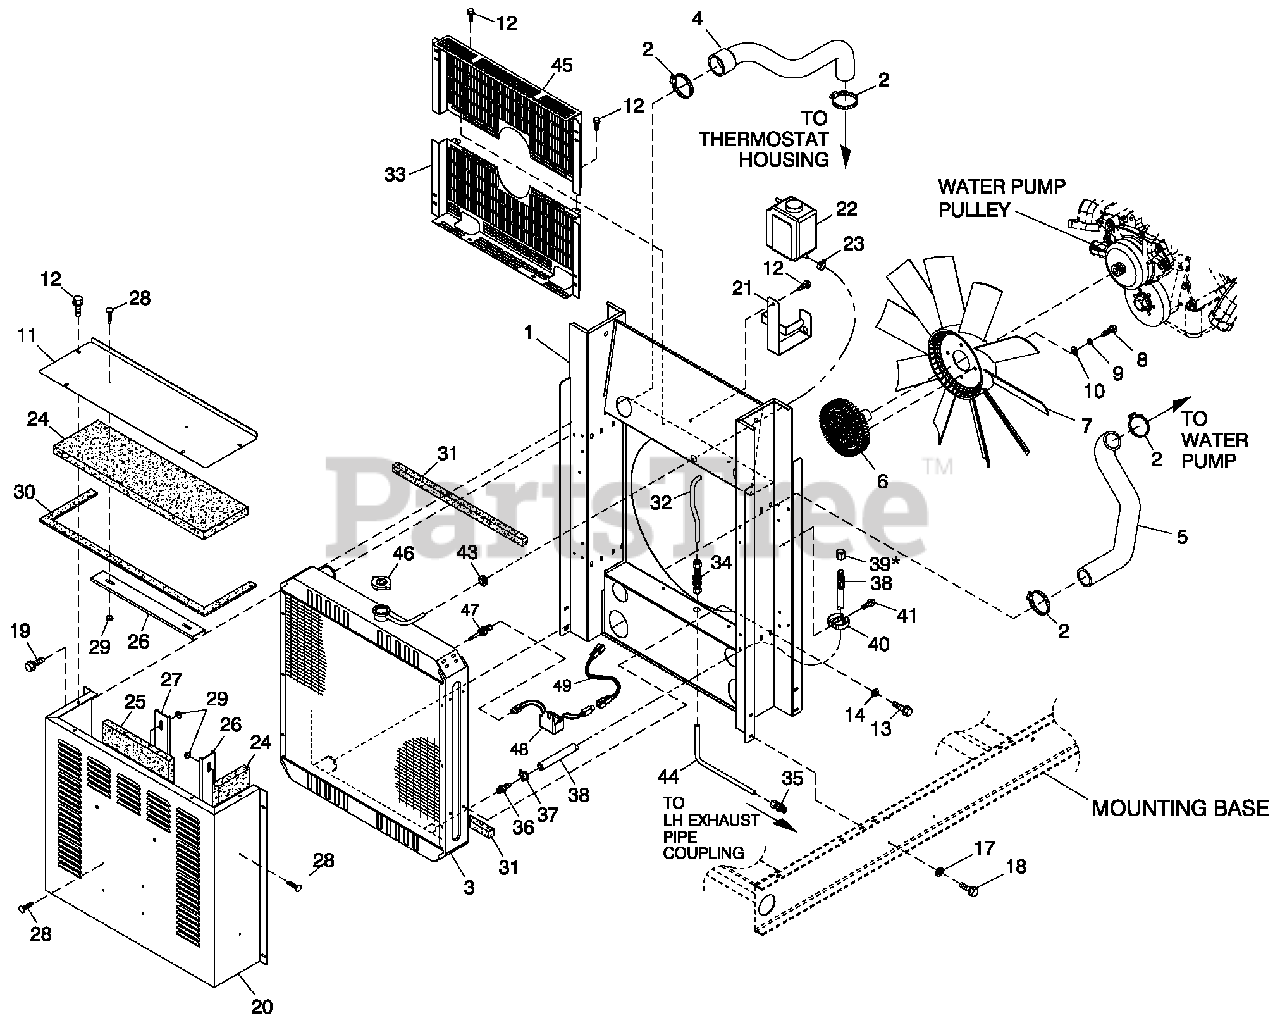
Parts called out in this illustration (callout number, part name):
1	WELDMENT RAD SUPPORT 3.9L C2
2	CLAMP HOSE #28 1.32-2.25
3	RADIATOR 598 X 568 X 49 CPL RH
4	HOSE UPPER RAD CPL C2 3.9L
5	HOSE LOWER RAD CPL C2 3.9L
6	CLUTCH COOLING FAN
7	FAN 22" DIA 10 BLADE
8	SCREW HHC M10-1.5 X 20 G8.8
9	WASHER LOCK M10
10	WASHER FLAT 3/8-M10 ZINC
11	DUCT INNER DISCHARGE TOP C2
12	SCREW THF M6-1 X 16 N WA Z/JS
13	SCREW HHFC M8-1.25 X 20 W/M6
14	WASHER LOCK M8-5/16
17	WASHER LOCK M6-1/4
18	SCREW HHFC M6-1.0 X 20 G8.8
19	SCREW HWHTF M6-1.0 X 16
20	DUCT INNER DISCHARGE C2
21	BRKT COOLANT RECOVERY TANK
22	TANK COOLANT RECOVERY
23	CLAMP HOSE BAND 1/4
24	INSULATION INNER DUCT
25	INSUL DUCT SIDE OR INNER DUCT
26	RETAINER INSULATION (450)
27	RETAINER INSULATION (220)
28	INSULATION RETAINMENT HANGER
29	WASHER SELF LOCKING DOME
30	FOAM STRIP 3/4" WIDE X 3/16" THK (46” LG)
31	TAPE FOAM 1 X 1 (22.5” LG)
32	TUBE FAN CLUTCH PREHTR UPPR C2
33	GUARD FAN C2 CPL, BOTTOM
34	FTG CMPN BLKHD 3/8" OD TUBE BRS
35	FTG CMPR 3/8TUBE X 3/8 NPT W/FERL
36	BARBED STR 3/8 NPT X 3/8
37	CLAMP HOSE .38-.87
38	HOSE DRAIN ASSY 28"
39	CAP HEX 1/4 NPT BRASS
40	SPRING CLIP HOLDER .37-.62
41	SCREW HHTT M4-0.7 X 8 BP
43	GROMMET .75 X .12 X .50
44	TUBE FAN CLUTCH PREHTR LOWR C2
45	GUARD FAN C2 CPL, TOP
46	CAP RADIATOR 13 PSI
47	PROBE COOLANT LEVEL 3/8 NPTF
48	ASSY PCB WATERLEVEL SNSRINTFC
49	HARNESS WATER LEVEL EXTENSION
